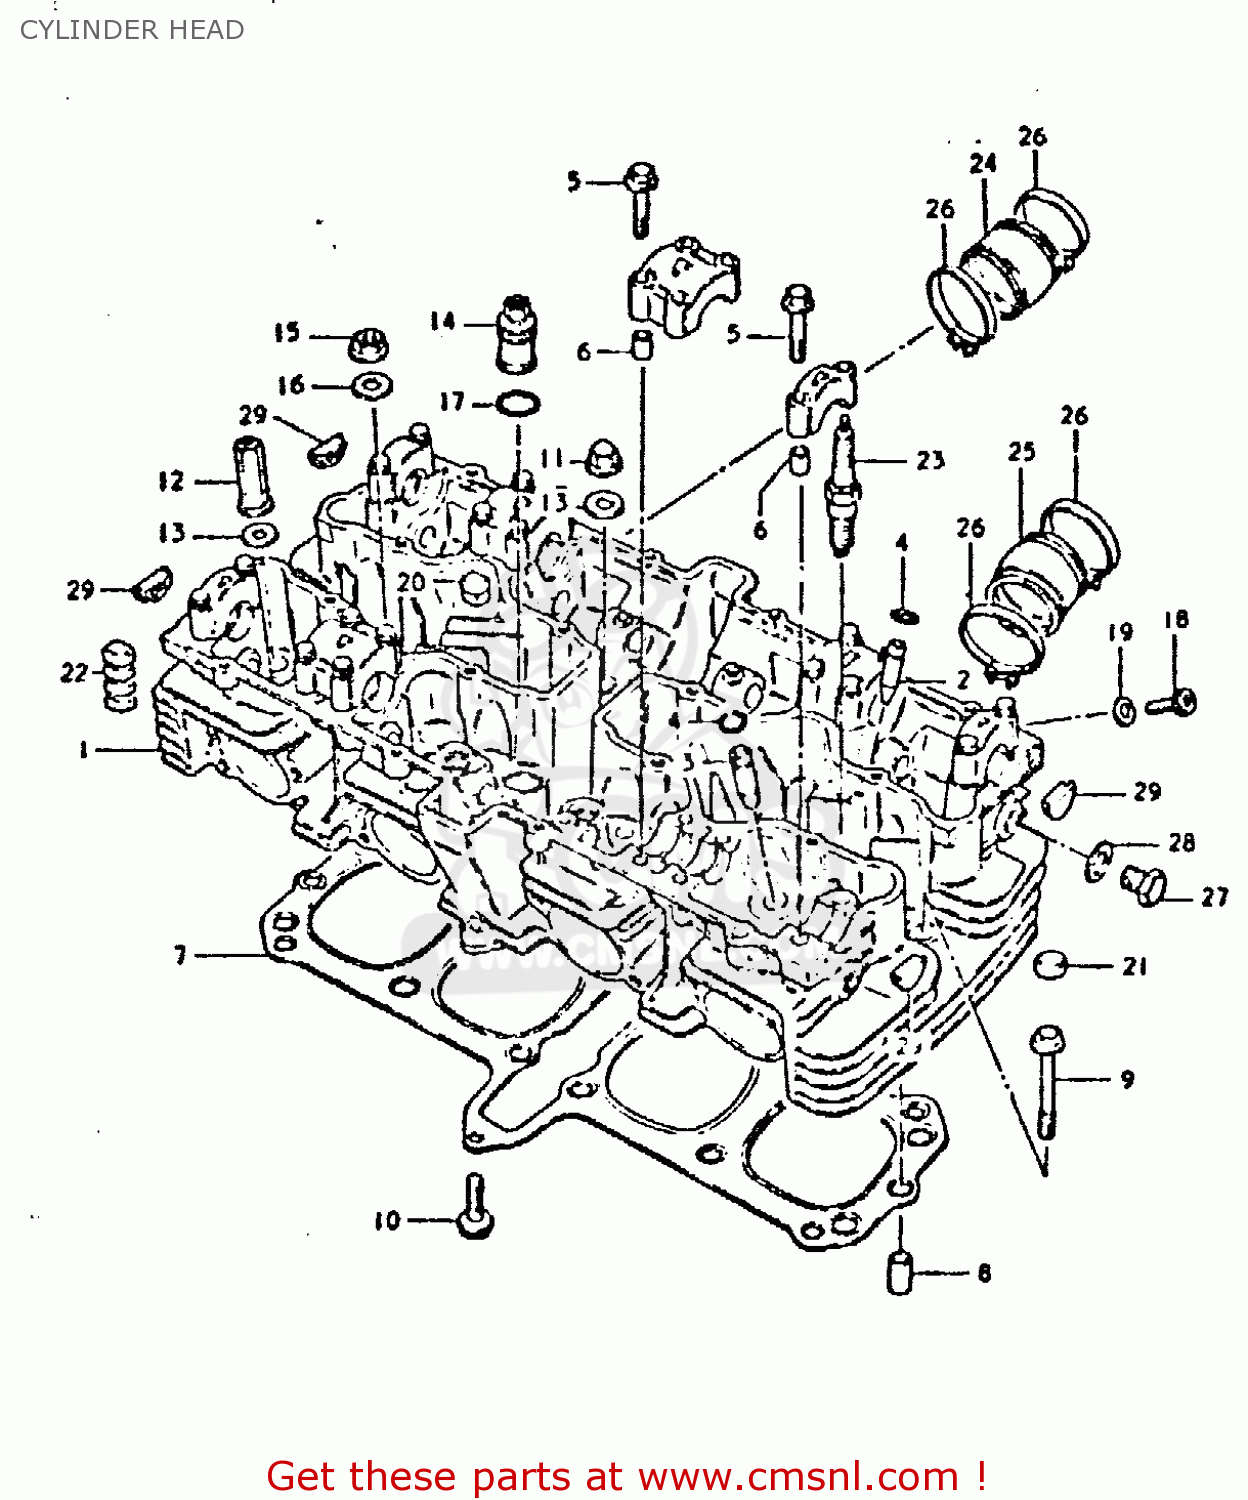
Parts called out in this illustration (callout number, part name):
1	HEAD ASSEMBLY,CYLINDER
2	GUIDE,INTAKE VALVE
3	GUIDE,INTAKE VALVE
4	RING,SNAP
5	BOLT(6X39)
6	PIN(6.2X8X11)
7	GASKET,CYLINDER HEAD (MCA)
8	PIN
9	BOLT
10	BOLT
11	NUT
12	NUT
13	GASKET (NAS)
14	NUT,CYLINDER HEAD SEAL
15	NUT
16	WASHER(10.5X22X2.3)
17	O RING(D:2.4,ID:16.8)
18	BOLT
19	GASKET(5.3X9.3X1.2) (NAS)
20	PAD
21	PAD,CYLINDER HEAD
22	PAD,CYLINDER
23	SPARK PLUG DR8ES-L
24	PIPE,INTAKE,R
25	PIPE,INTAKE
26	CLAMP
27	PLUG (14X12)
28	GASKET(14X19.2X2) (NAS)
29	PLUG
